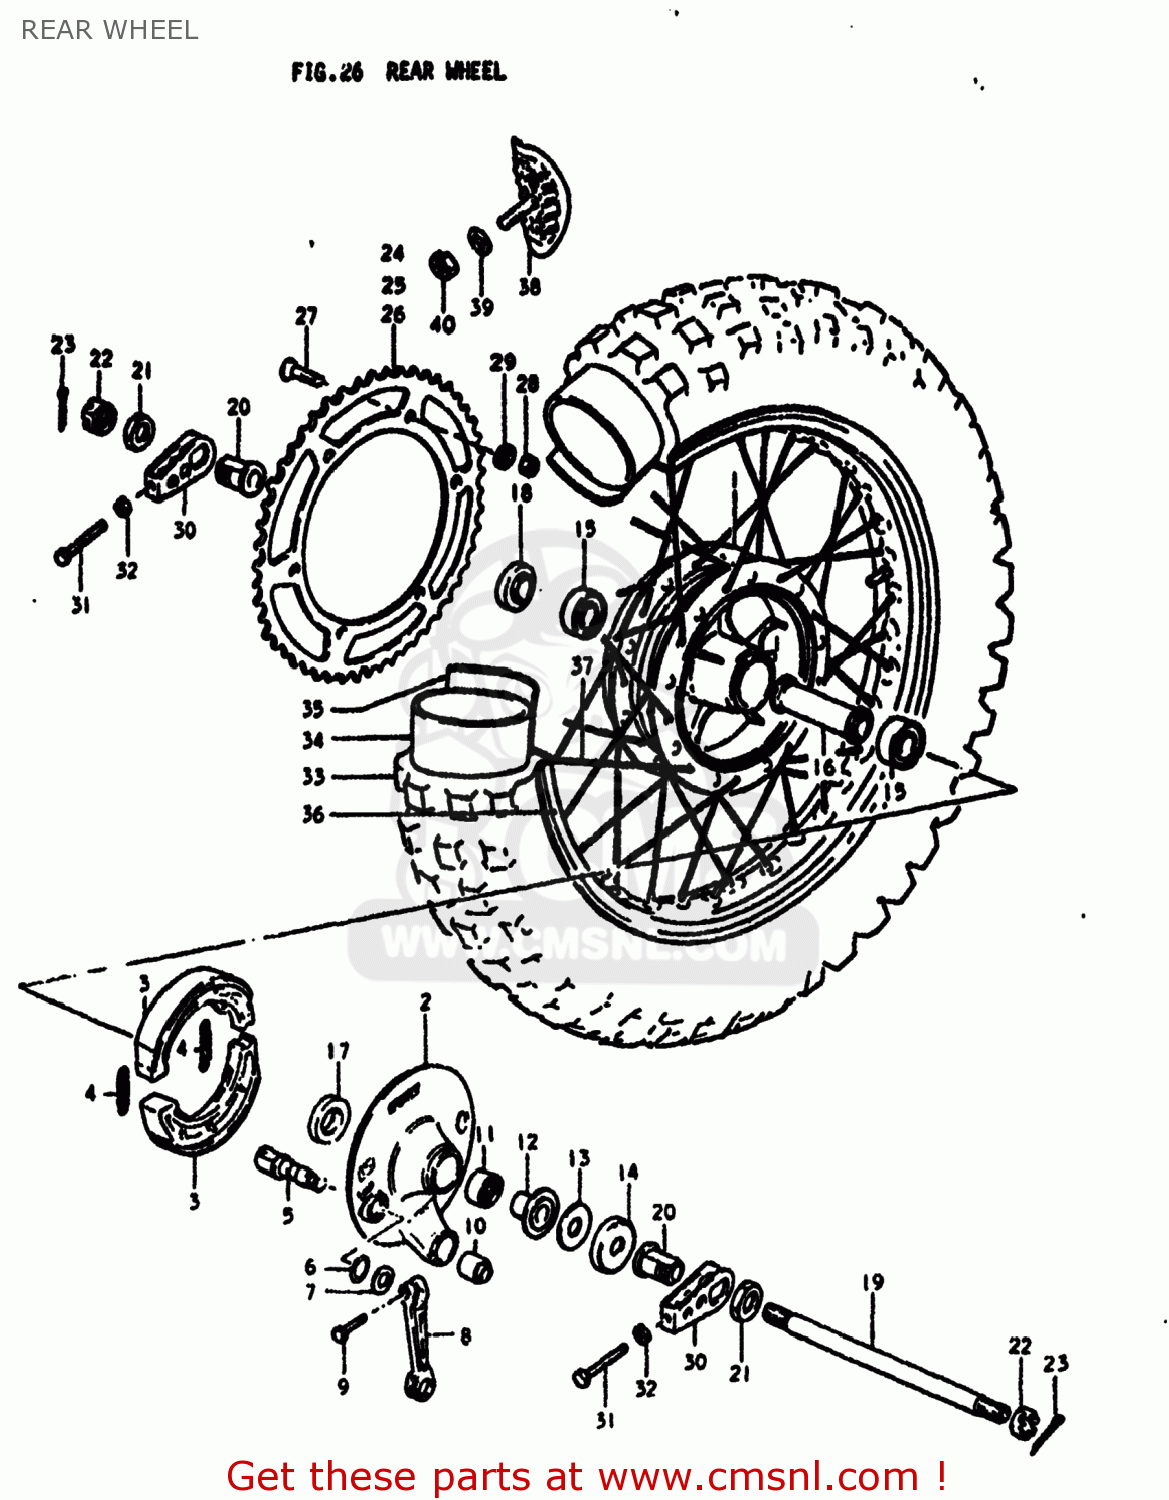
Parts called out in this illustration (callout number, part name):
1	HUB,REAR
2	PANEL,REAR HUB
3	SHOE,BRAKE
4	SPRING
5	CAM,FR BRAKE
6	O RING(D:2.5,ID:11.4)
7	WASHER(12.5X20X1)
8	LEVER,REAR BRAKE CAM
9	BOLT
10	BUSH
11	BEARING(22X29X25)
12	SPACER,REAR HUB PANEL
13	WASHER
14	COVER, PANEL DUST SEAL
15	BEARING
16	SPACER,REAR HUB BEARING
17	SPACER,REAR AXLE,RIGHT
18	SPACER,REAR AXLE,RIGHT
19	AXLE,REAR
20	SPACER,CHAIN ADJUSTER
21	NUT
22	NUT
23	PIN 30X40
24	SPROCKET,REAR
25	SPROCKET,REAR
26	SPROCKET,REAR
27	SCREW
28	NUT
29	WASHER
30	ADJUSTER,CHAIN
31	BOLT
32	NUT
33	TIRE
34	TUBE,INNER
35	PROTECTOR,WHEEL,INNER
36	RIM,REAR WHEEL
37	SPOKE SET,REAR
38	STOPPER,BEAD
39	WASHER
40	NUT
